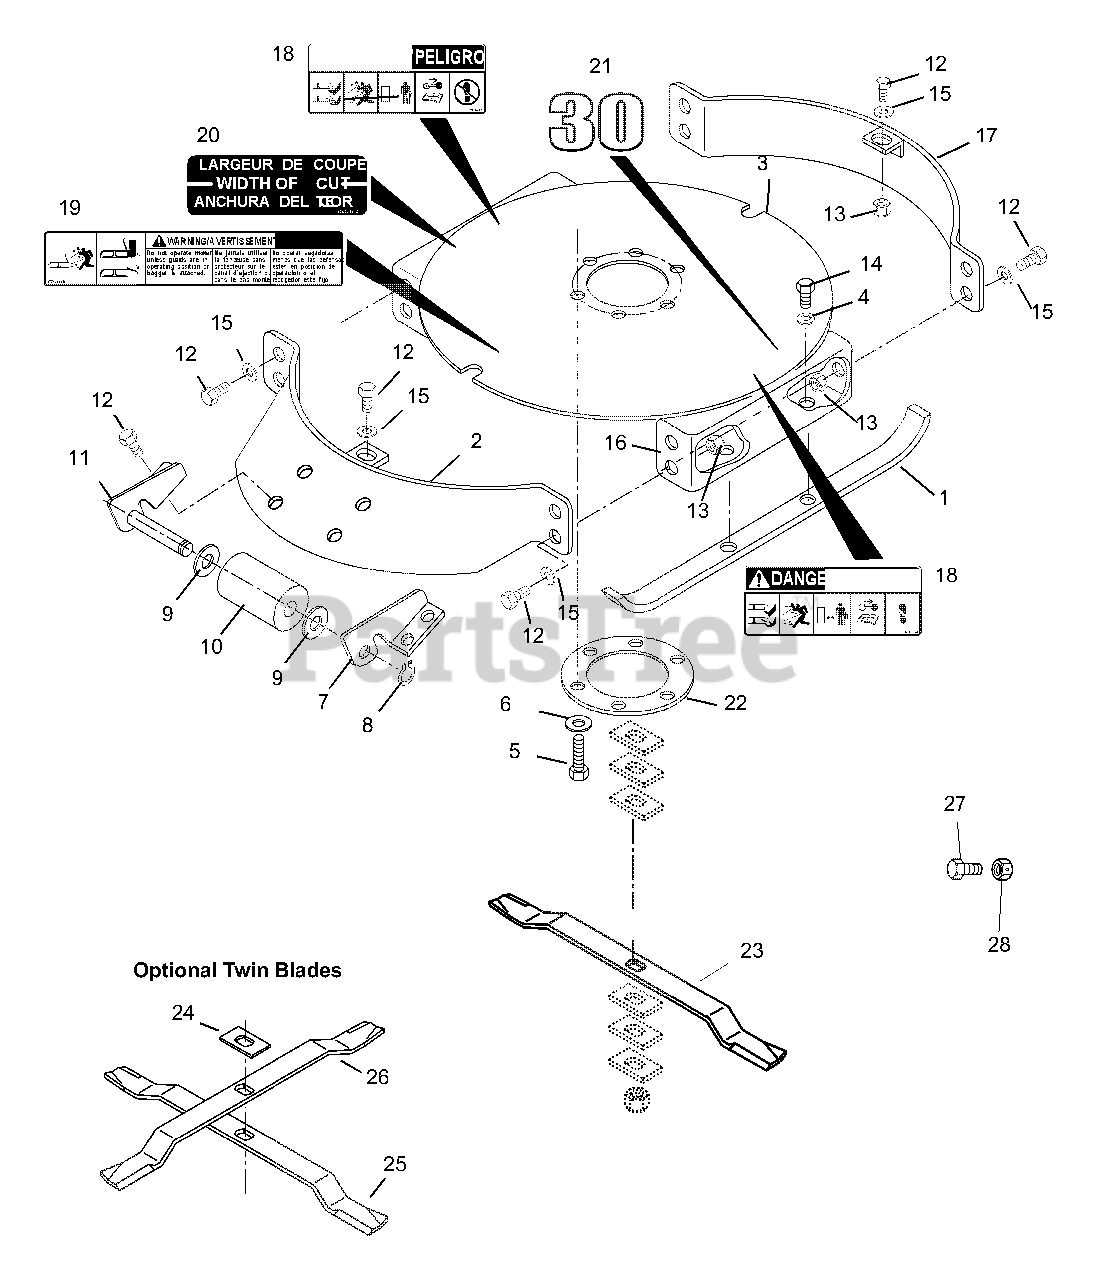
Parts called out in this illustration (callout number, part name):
1	Skid-Rotary Mower
2	Fender-Front 30" Mower
3	Deck-Weldment 30 in.
4	Washer-Lock .31
5	Bolt, Hex .50-13 x 1.75 Grade 5
5	Bolt, Hex .50-13 x 3.25 Grade 5
6	Washer-Flat-Steel .563 x 1.38 x .109
7	Bracket-Wheel L-H
8	Ring-Retaining-External .625 x .042
9	Washer-Flat-Stainless Steel .656 x 1.25 x .1
10	Roller-Gage
11	Weldment-Bracket
12	Bolt-Hex .31-18 x 1.00 Grade 5
13	Nut-Locking Nylon .31-18
14	Bolt-Hex .31-24 x .625
15	Washer, Flat .312 x .734 x .065
16	Panel Skid
17	Weldment-Rear Fender
18	Decal, Mower Pan Head Danger
19	Decal, Warning
20	Decal, Width of Cut
21	Decal, 30
22	Counterweight, 30" Deck
23	Rotary Mower Blade .375"
24	Spacer-Cutting Height .125
25	Blade, 30" Mower-Thin
26	Blade, 30" Mower-Thin, Cross Slot
27	Bolt, Hex .25-20 x .50 Grade 5
28	Nut, Locking, Center .25-20
